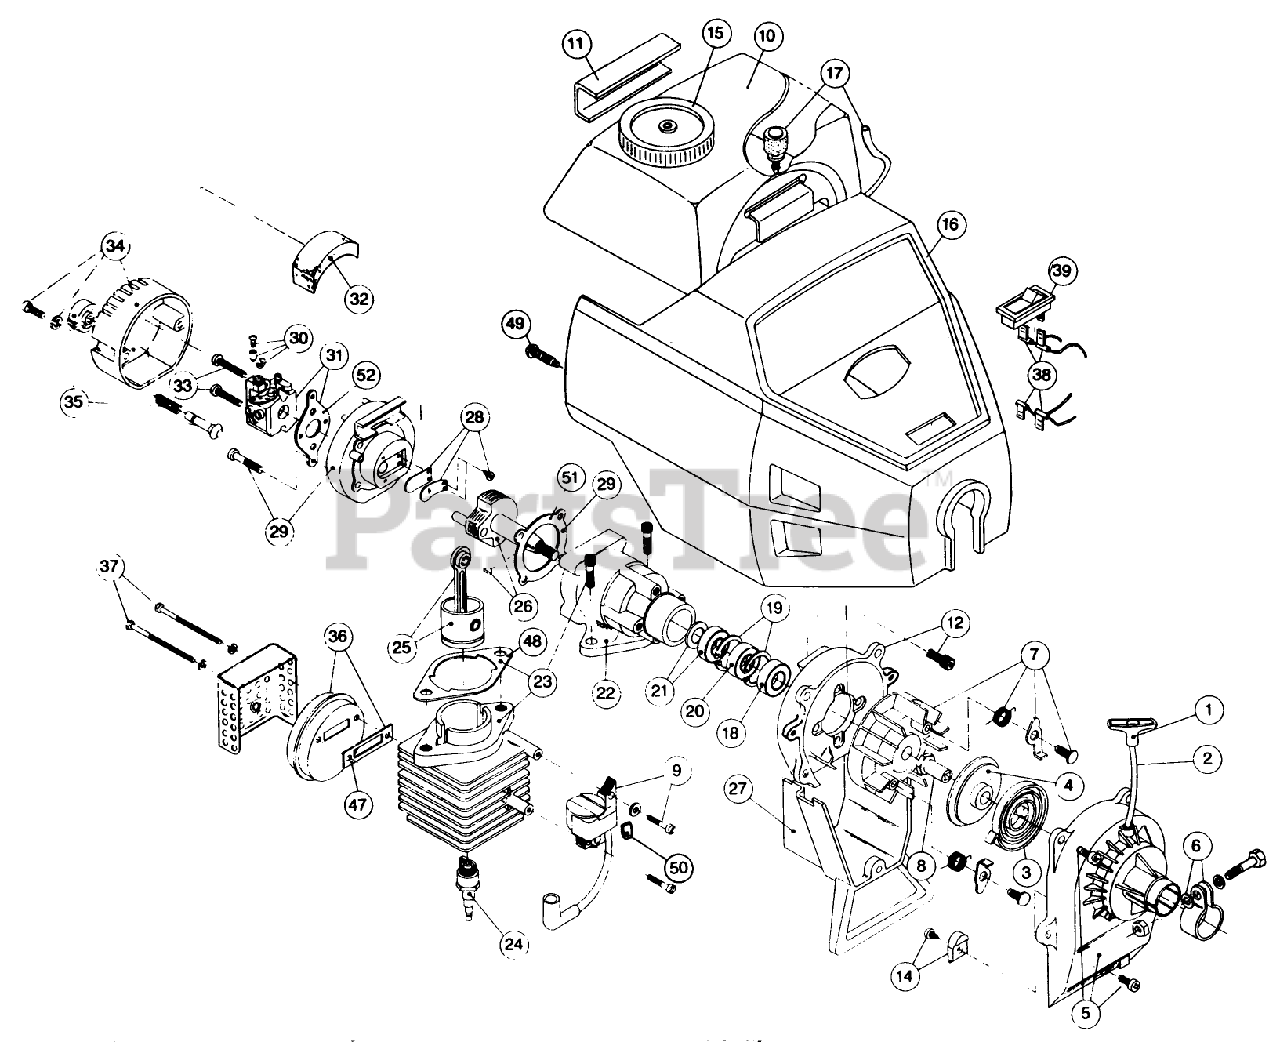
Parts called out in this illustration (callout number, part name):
8	SQUARE DRIVE NUT
12	SHROUD ASM
13	FRONT MOUNTING PAD
17	FUEL LINE ASM
18	OUTER BEARING
21	INNER BEARING ASM
24	SPARK PLUG
30	Throttle adjustment assembly
37	MUFFLER MOUNTING BOLTS
52	CARB.GASKET
